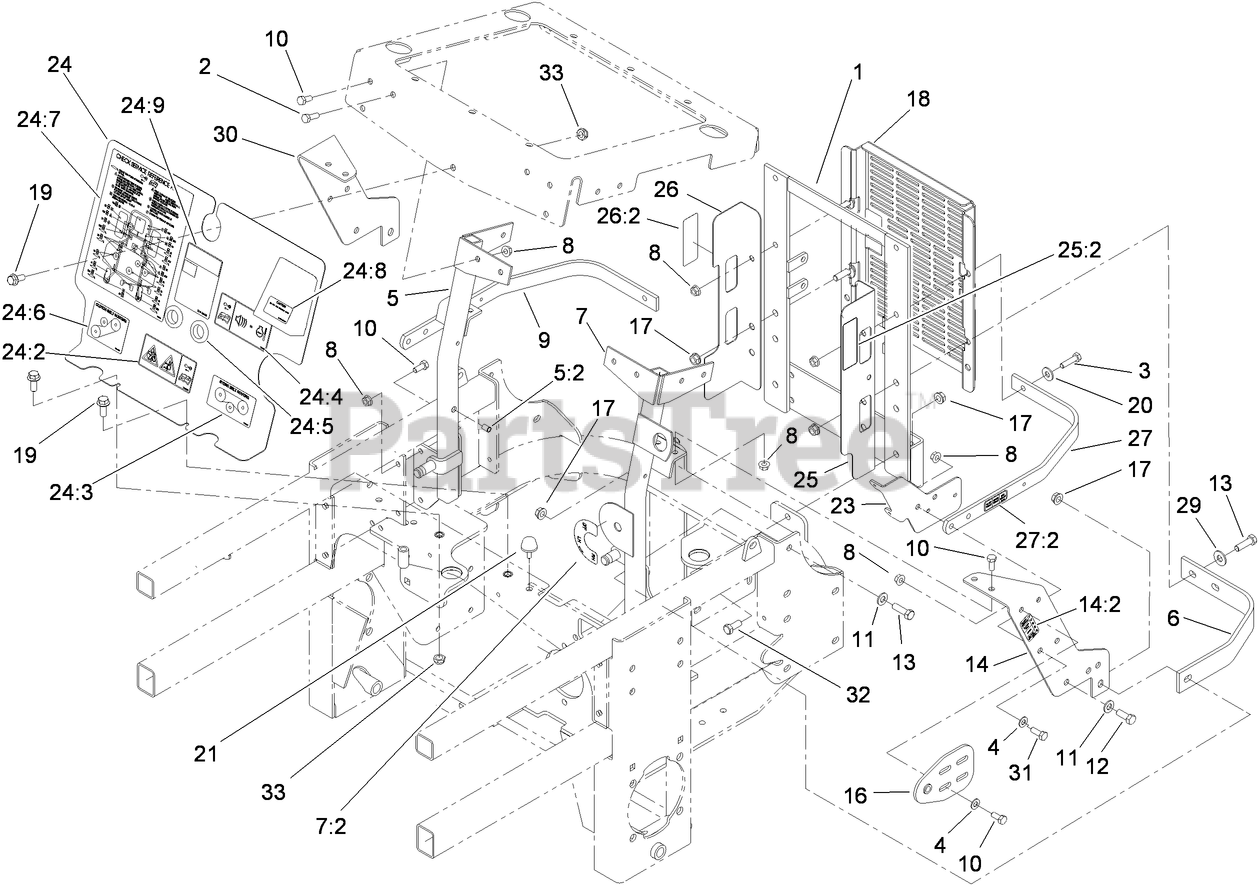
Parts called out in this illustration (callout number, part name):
1	SUPPORT-RADIATOR, REAR
2	SCREW-HH
3	SCREW-HH
4	WASHER-PLAIN
5	RH RADIATOR BRACE ASM
5:2	NUT-CLINCH
6	STRAP-GUARD
7	LH RADIATOR BRACE ASM
7:2	DECAL-VALVE, FUEL
8	NUT-HF
10	SCREW-HH
11	WASHER-FLAT
12	SCREW-HH
13	SCREW-HH
14	LH SUPPORT BRACKET ASM
14:2	DECAL-FUSE
16	PLATE-PIVOT, HOOD
17	NUT-HHF, WHIZ
18	SHIELD-COOLER
19	SCREW-HHF
20	WASHER-FLAT
21	BUMPER-RUBBER
23	BRACKET-RELAY, FUSE
24	FRONT ENGINE SHIELD ASM
24:2	DECAL-DANGER, ROTATING DEVICES
24:3	DECAL-ROUTING, HYDRO BELT
24:4	DECAL- WARNING, BUZZER
24:5	GROMMET-RUBBER
24:6	DECAL-ROUTING, CLUTCH BELT
24:7	DECAL-CHECK, SERVICE
24:8	DECAL-CAUTION
24:9	DECAL-COOLANT
25	GUARD-FAN, LH (CE)
25:2	DECAL-DANGER
26	GUARD-FAN, RH (CE)
26:2	DECAL-DANGER
27	TOP STRAP ASM
27:2	DECAL-RELAY
29	WASHER-FLAT
30	BRACKET-SUPPORT, RH
31	SCREW-HH
32	SCREW-HH
33	NUT-LOCK, NI
